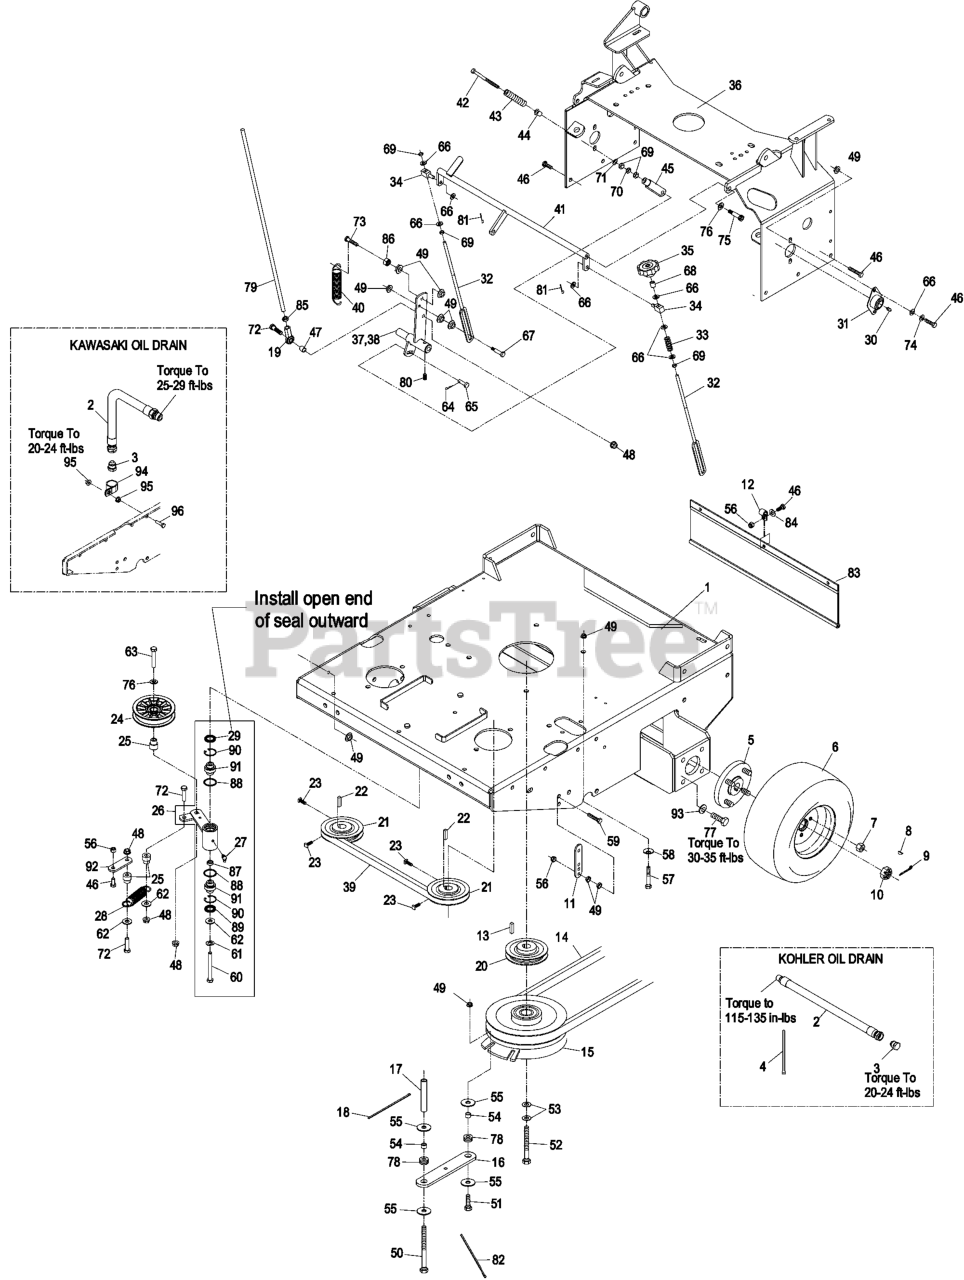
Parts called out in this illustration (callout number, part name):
4	TIE-PLASTIC
6	ASM, DRIVE TIRE
7	NUT-LUG
8	KEY-WOODRUFF
9	PIN-COTTER
10	NUT-HEX, SLOTTED
11	TAB-SPRING, EXTENSION
12	CLIP-LOOM
14	BELT,B 83.65
15	CLUTCH ASM
16	STRAP-CLUTCH, BRAKE
17	SPACER,SHIELD
18	TIE-CABLE
19	JOINT-BALL END, LH
20	PULLEY
21	SHEAVE ASM
23	SCREW-SET
24	PULLEY-IDLER, FLAT
25	BUSHING-IDLER
26	KIT,IDLER ARM W/BRGS.
27	FITTING-GREASE, 90 DEG
28	SPRING-EXTENSION
29	SEAL-LIP, SINGLE
30	FITTING-GREASE
31	BEARING-FLANGE, SIDE
32	LINK,SPEED CONTROL
33	SPRING-COMPRESSION
35	KNOB-TRACKING
36	WLD,FUEL TANK SUPPORT TT
37	WLD,LH CONTROL ARM
39	BELT,COG A-59.5
40	SPRING-EXTENSION
41	WLD,CRANK SPEED CNTRL
42	BOLT-RETURN, NEUTRAL
43	SPRING,COMPRESSION (NEUT)
44	BUSHING-FLANGED
45	YOKE-ADJUSTABLE
46	SCREW-HH
47	TUBE,PUMP LINK SPACER
48	NUT-HHF, WHIZ
49	NUT-HF
50	SCREW-HH
51	SCREW-HH
52	SCREW-HH
53	WASHER-SPRING
56	NUT-LOCK, NI
57	SCREW-HH
58	WASHER-SPRING
59	BOLT-TAP, HH
60	SCREW-HH
61	WASHER-LOCK
62	WASHER-FLAT
63	SCREW-HH
64	PIN-COTTER
65	PIN-CLEVIS
66	WASHER-PLAIN
67	SCREW-HH
69	NUT-HEX
70	NUT-JAM
71	WASHER-FLAT
72	SCREW-HH
73	SCREW-HH
74	WASHER-LOCK
75	SCREW-HSH
76	WASHER-FLAT
77	SCREW-HH
78	GROMMET
79	LINK,DRIVE (PLTD)
80	SCREW-SET
81	PIN-COTTER
82	TIE-PLASTIC
83	SHIELD,DRAG
84	WASHER-FLAT
85	NUT-HEX JAM, LH
86	NUT-JAM
89	SEAL-LIP, DOUBLE
90	RING-SNAP
91	BEARING-SPHERICAL
92	ARM-LIFT, DECK
93	WASHER-BELLEVILLE
94	CLIP-LOOM
96	SCREW-HH
